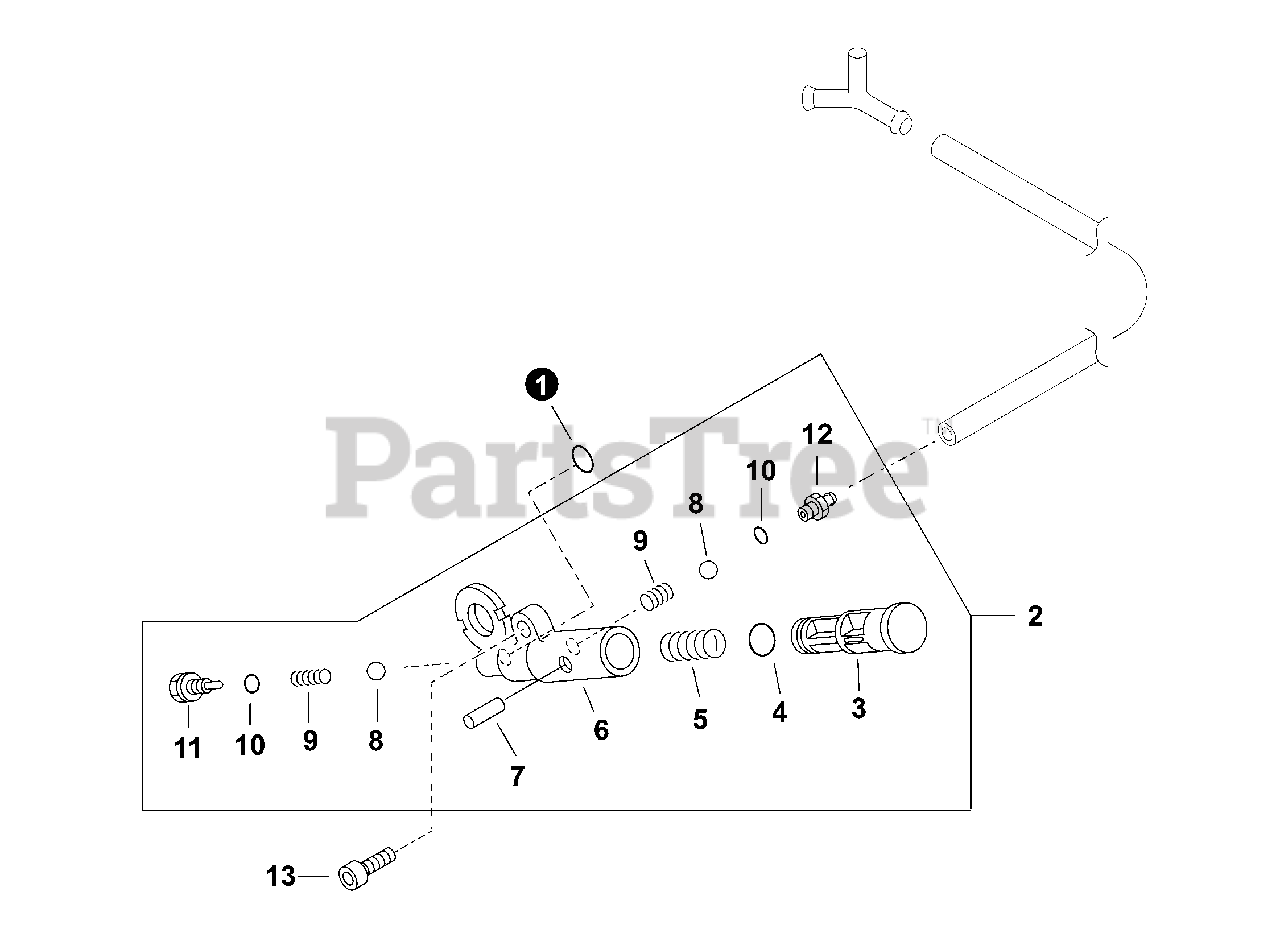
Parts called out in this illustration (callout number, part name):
1	O-RING 3
2	OIL PUMP ASSY
3	PISTON, OIL PUMP
4	O-RING 7 MM
6	BODY, OIL PUMP
7	PIN, SPRING 2×16
8	VALVE, BALL
9	SPRING, COMPRESSION
11	ADAPTOR, OIL PUMP
12	CONNECTOR, PIPE
13	BOLT 5×20
